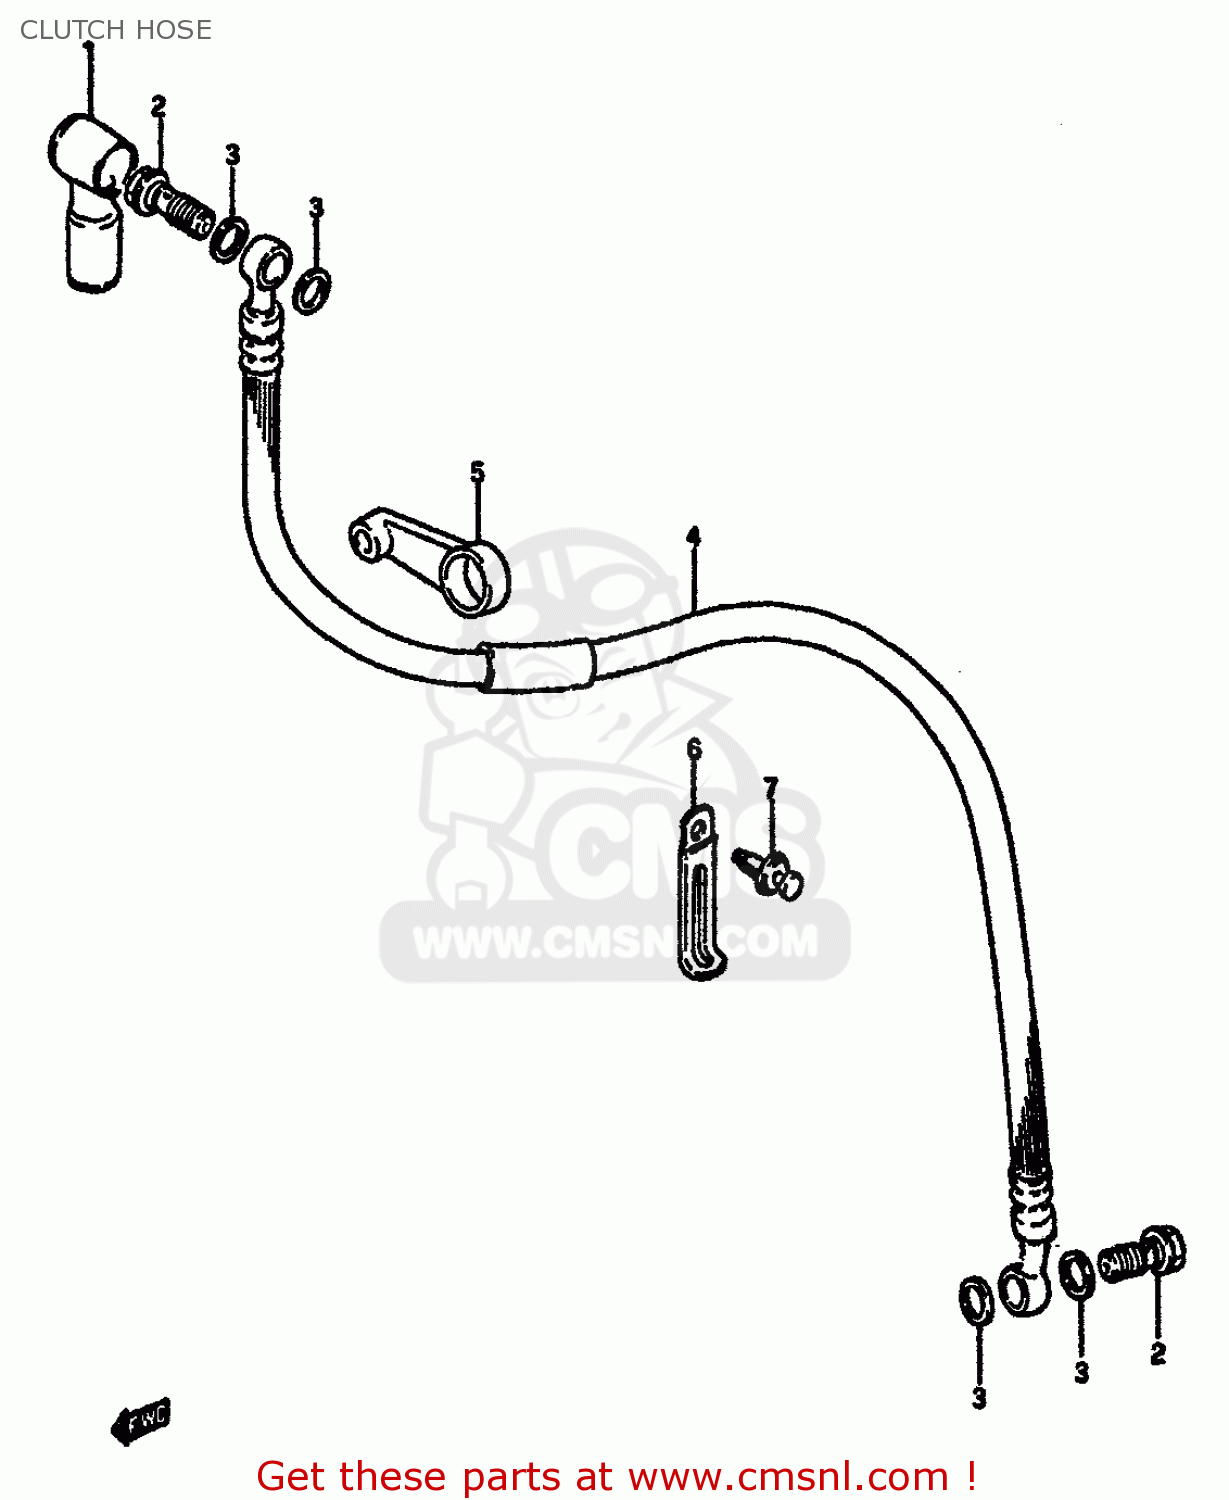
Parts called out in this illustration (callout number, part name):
1	BOOT,MASTER CYLINDER
2	BOLT UNION
3	WASHER(10X15X1.5)
4	HOSE,CLUTCH
5	CLAMP,CLUTCH HOSE NO.2
6	CLAMP
7	CLIP
